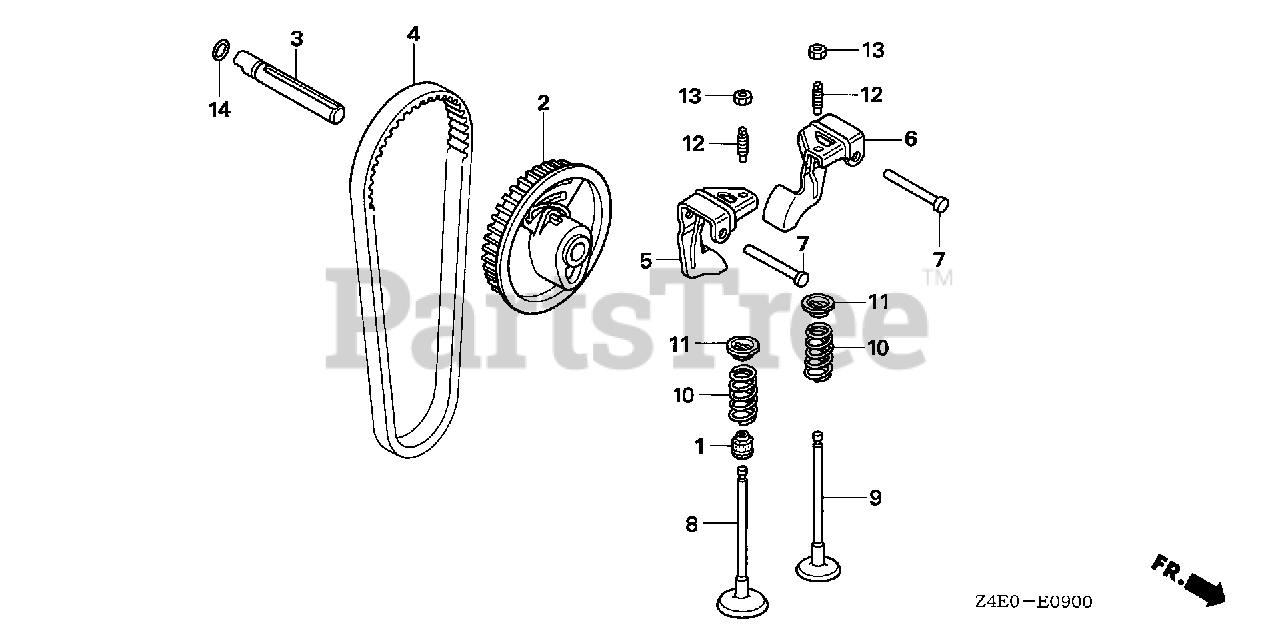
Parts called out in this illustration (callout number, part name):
1	SEAL, VALVE STEM
2	PULLEY, CAMSHAFT
3	SHAFT, CAM PULLEY
4	BELT, TIMING (61YU7 G-200)
5	ARM, IN. VALVE ROCKER
6	ARM, EX. VALVE ROCKER
7	SHAFT, ROCKER ARM
8	VALVE, IN.
9	VALVE, EX.
10	SPRING, VALVE
11	RETAINER, VALVE SPRING
12	SCREW, TAPPET ADJUSTING
13	NUT, TAPPET ADJUSTING
14	O-RING (6.8X1.9) (ARAI)
